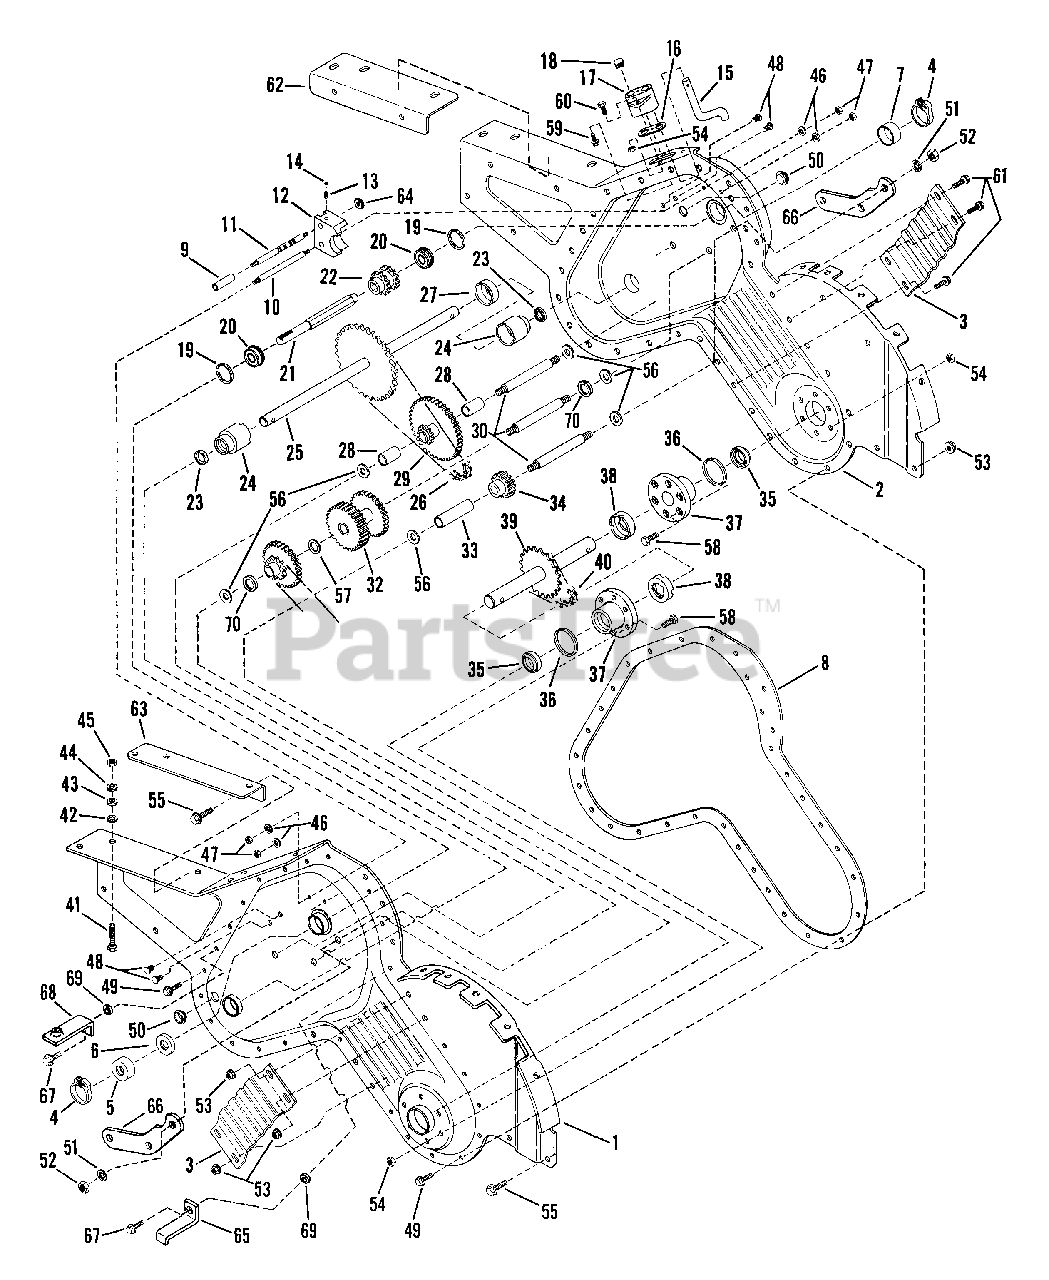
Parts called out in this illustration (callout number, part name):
1	CASE, Left Hand Tiller
2	CASE, Right Hand Tiller
3	REINFORCEMENT, Case
4	* CLAMP, Speedy
5	* SEAL, Boot Oil
6	* SEAL, Oil
7	* SEAL, Cap
8	GASKET, Main Case
9	SPACER, Main Shaft
10	PIN, Guide
11	SHAFT, Main Detent
12	FORK, Primary Shaft
13	SPRING
14	BALL
15	CRANK, Shift
16	GASKET, Shift Arm
17	PIVOT, Shift Arm
18	* PLUG, 1/2" Button
20	BEARING
21	* SHAFT, Input
22	PINION, Input
23	SEAL, Oil
24	BEARING, Axle
25	* WELDMENT, Axle
26	CHAIN, Traction #40
27	SPACER, Wheel Shaft
29	GEAR & SPROCKET
30	SHAFT, Gear
31	** ASSEMBLY, Tine Drive Gear
32	** ASSEMBLY, Wheel Drive Gear
33	SPACER, Reverse
34	** ASSEMBLY, Reverse Idler
35	SEAL, Oil
36	O-RING
37	BEARING, Tine Shaft
38	SPACER, Tine Shaft
39	* STRUCTURE, Tine Shaft
40	CHAIN, Tine #40
41	SCREW, 5/16-24 x 1 3/4" Hex Hd. Cap
42	RETAINER, 5/16 Bolt
43	WASHER, 5/16 Flat
44	LOCKWASHER, 5/16 Split
45	NUT, 5/16-24 Hex
46	WASHER, 1/4 Int. Tooth Lock
47	NUT, 1/4-20 Hex
48	* FASTENER, Ratchet
49	SCREW, 5/16-18 x 1/2" Self-Tapping
50	PLUG
51	WASHER, 7/16 Int. Tooth Lock
52	NUT, 7/16-20 Hex
53	LOCKNUT, 5/16-18 Hex Flange
54	LOCKNUT, 1/4-20 Hex
55	BOLT, 5/16-18 x 1/2" Hex Flg. Lock
58	SCREW, 1/4-20 x 5/8" Hex Hd. Cap
59	* SCREW, 1/4-20 x 1/2" Self-Tapping
60	SCREW, 1/4-20 x 3/4" Self-Tapping
61	BOLT, 5/16-18 x 3/4" Hex. Flg. Lock
62	REINFORCEMENT, R.H. Frame
63	REINFORCEMENT, L.H. Frame
64	* WASHER, Shim
65	BRACE, Belt Cover
66	SIDE PLATE
67	SCREW, 5/16-18 x 5/8" Self-Tapping
68	BRACKET, Belt Cover
69	SPACER, (IR 5002B)
70	WASHER, Shim
